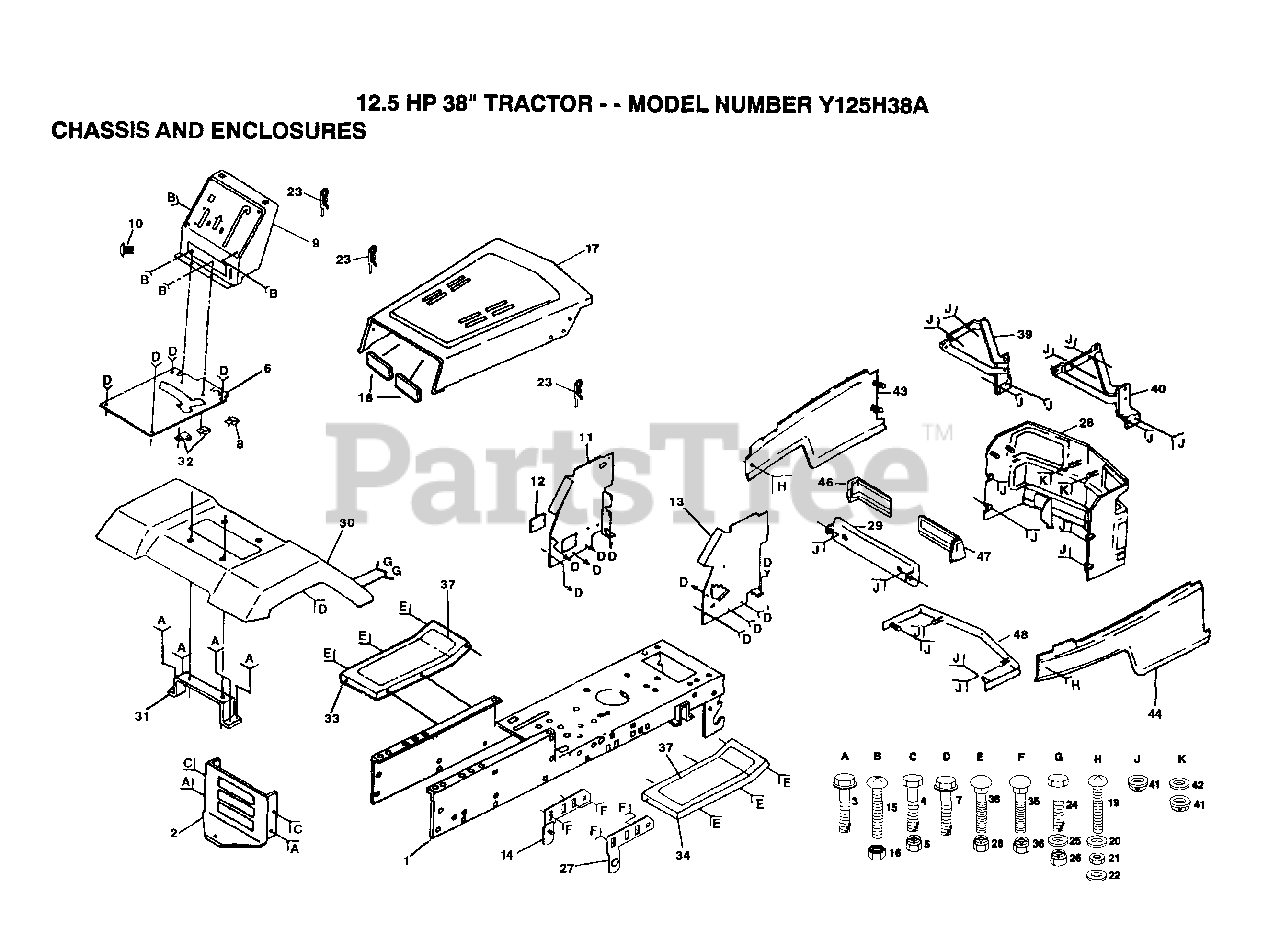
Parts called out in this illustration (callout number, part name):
1	CHASSIS ASM
2	DRAWBAR LT/YT
3	SCREW
7	SCREW LT
8	CLIP T
9	No Desciption for Part
10	PLUG BUTTON T
11	PANEL DASH LH
12	COVER ACCESS
14	BRKT ASM PIVOT LH
15	SCREW
19	"SCREW,SPECIAL"
21	RETAINER
22	"GROMMET,PLASTIC"
23	SPRING.RETAINER
25	WASHER
27	BRKT ASM PIVOT RH
32	"CLIP,INSULATOR"
35	BOLT
36	NUT
37	FOOTREST PAD
38	BOLT
39	"HINGE,HOOD,LH T"
40	"HINGE,HOOD,RH T"
41	PAL NUT LT
42	WASHER PM
43	SIDE PANEL ASM LH
44	SIDE PANEL ASM RH
48	STRAP ASM GRILL
